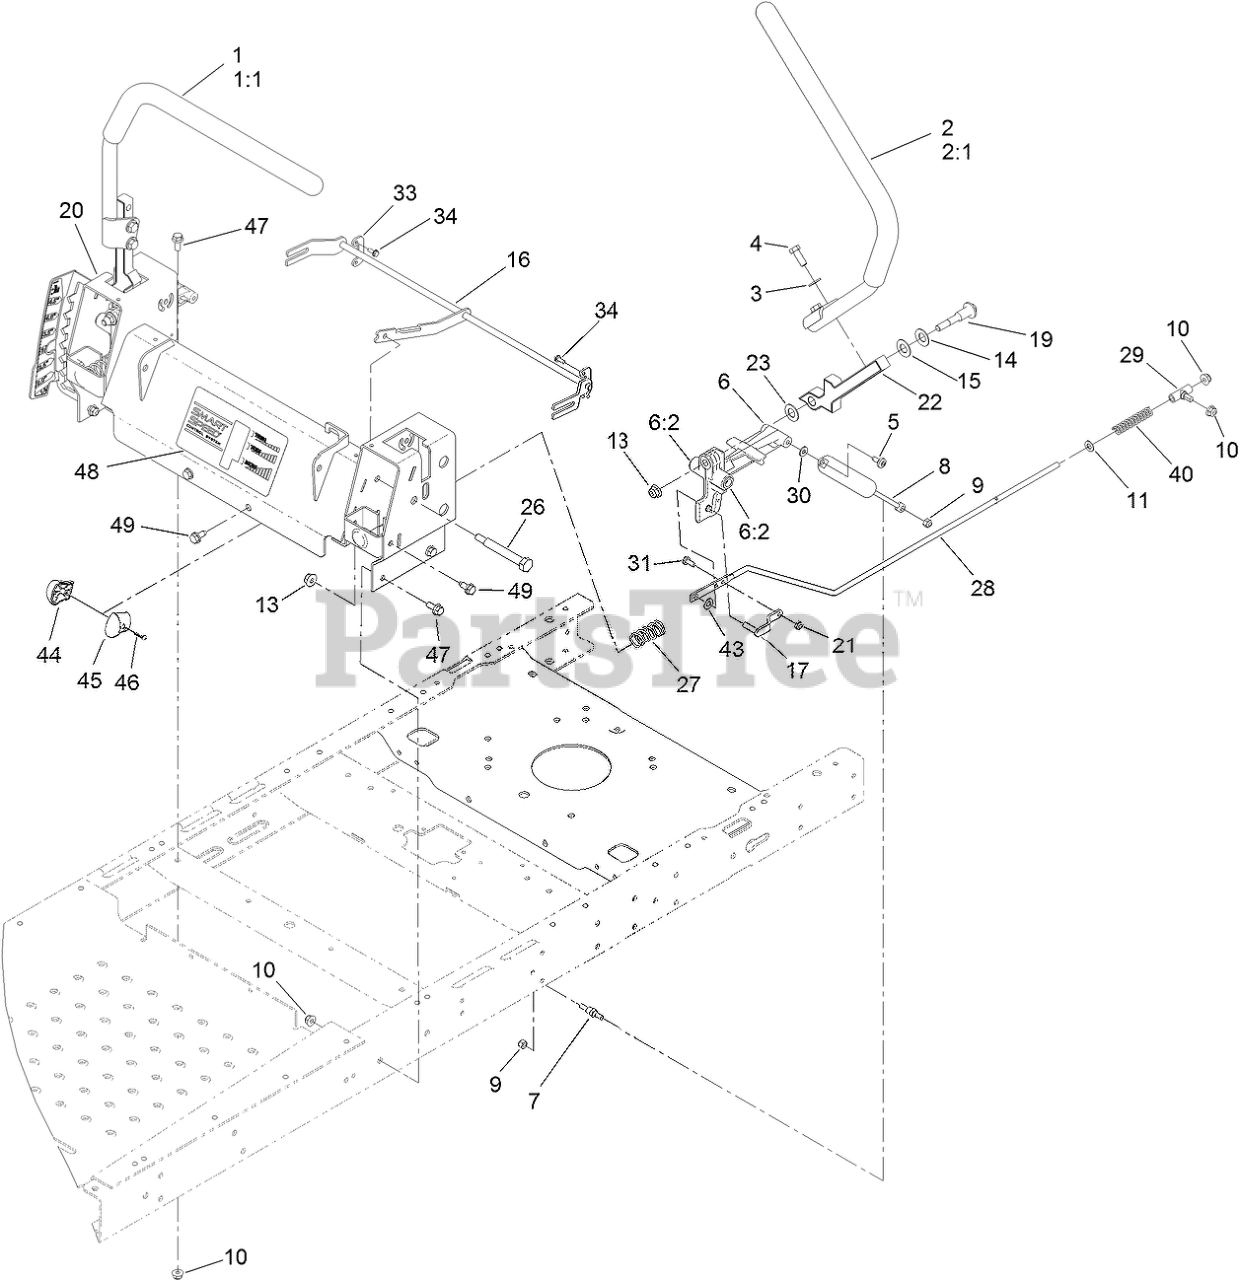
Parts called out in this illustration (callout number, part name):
1	HANDLE-CONTROL, RH
2	HANDLE-CONTROL, LH
3	WASHER-FLAT
4	SCREW-HH
5	SCREW-SHOULDER
6	ACTUATOR ARM ASM
6:2	BUSHING-FLANGE
7	STUD-DAMPER
8	DAMPER
9	NUT-LOCK, NI
10	NUT-HF, NI
11	WASHER-PLAIN
13	NUT-HF, NI
14	WASHER-BELLEVILLE
15	WASHER
16	SPEED CONTROL ASM
17	PIN-ROD, HYDRO
19	BOLT-PIVOT
20	CONTROL BOX ASM
21	NUT-LOCK, NI
22	LEVER-CONTROL
23	WASHER-NYLON
26	BOLT-PIVOT
27	SPRING-RETURN
28	ROD-HYDRO
29	MOUNT-ROD, HYDRO
30	WASHER
31	SCREW-HH
33	RETAINER
34	SCREW-TAPTITE
40	SPRING-RETURN, NEUTRAL
43	SPACER-NYLON
44	KNOB-RH
45	KNOB-LH
46	SCREW-PPH
47	SCREW-HHF
48	DECAL-CONTROL, SPEED
49	SCREW-HWHTF
